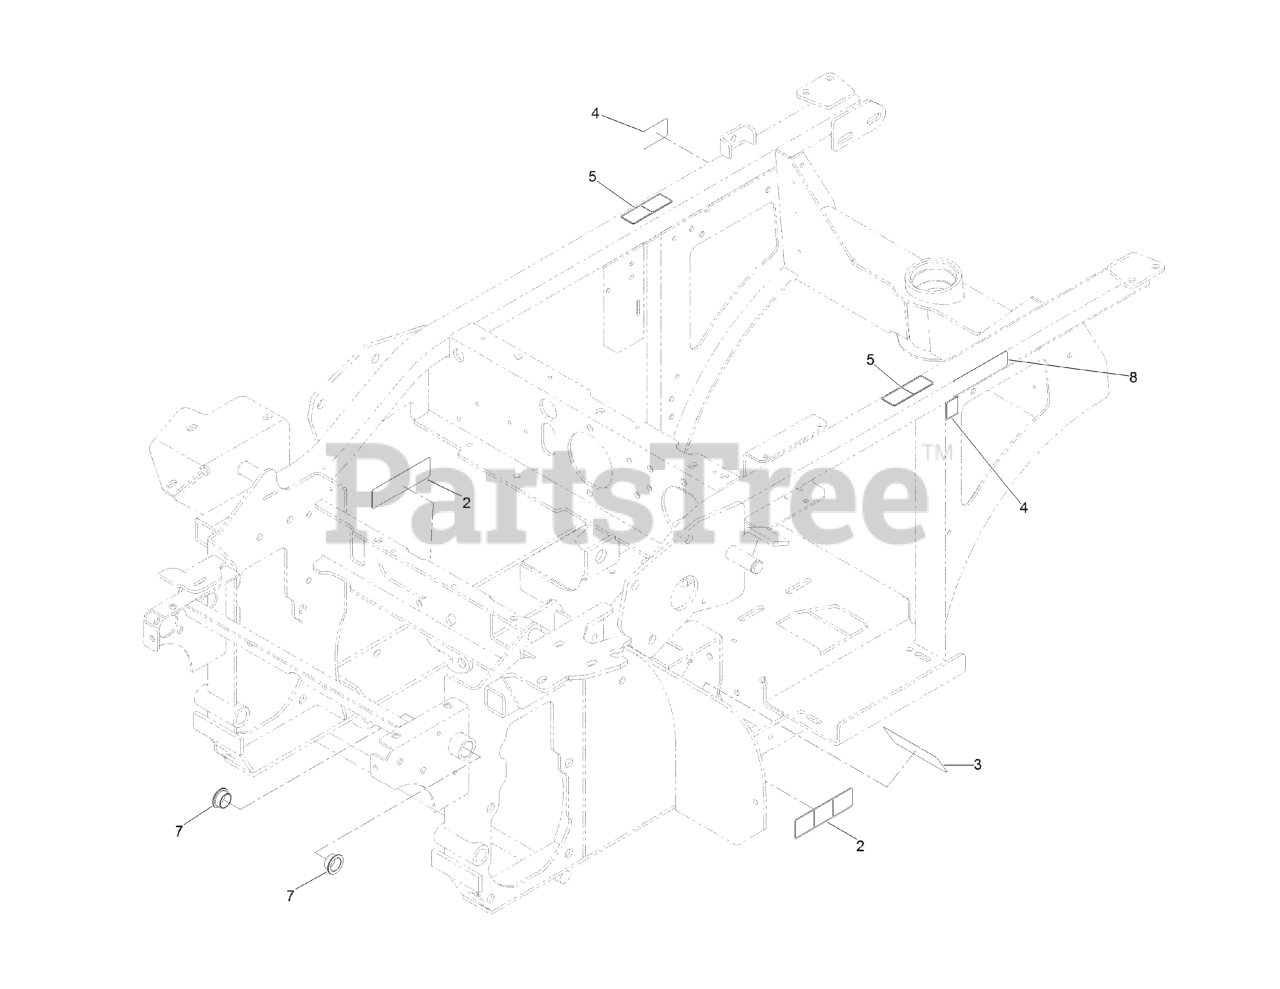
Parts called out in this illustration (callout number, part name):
2	DECAL-COVER, MISSING
3	Decal-Adjustment, Clutch
4	DECAL-WARNING
5	DECAL-WARNING, PINCH POIN
7	BUSHING-BRONZE
8	DECAL-ARRESTOR, SPARK
